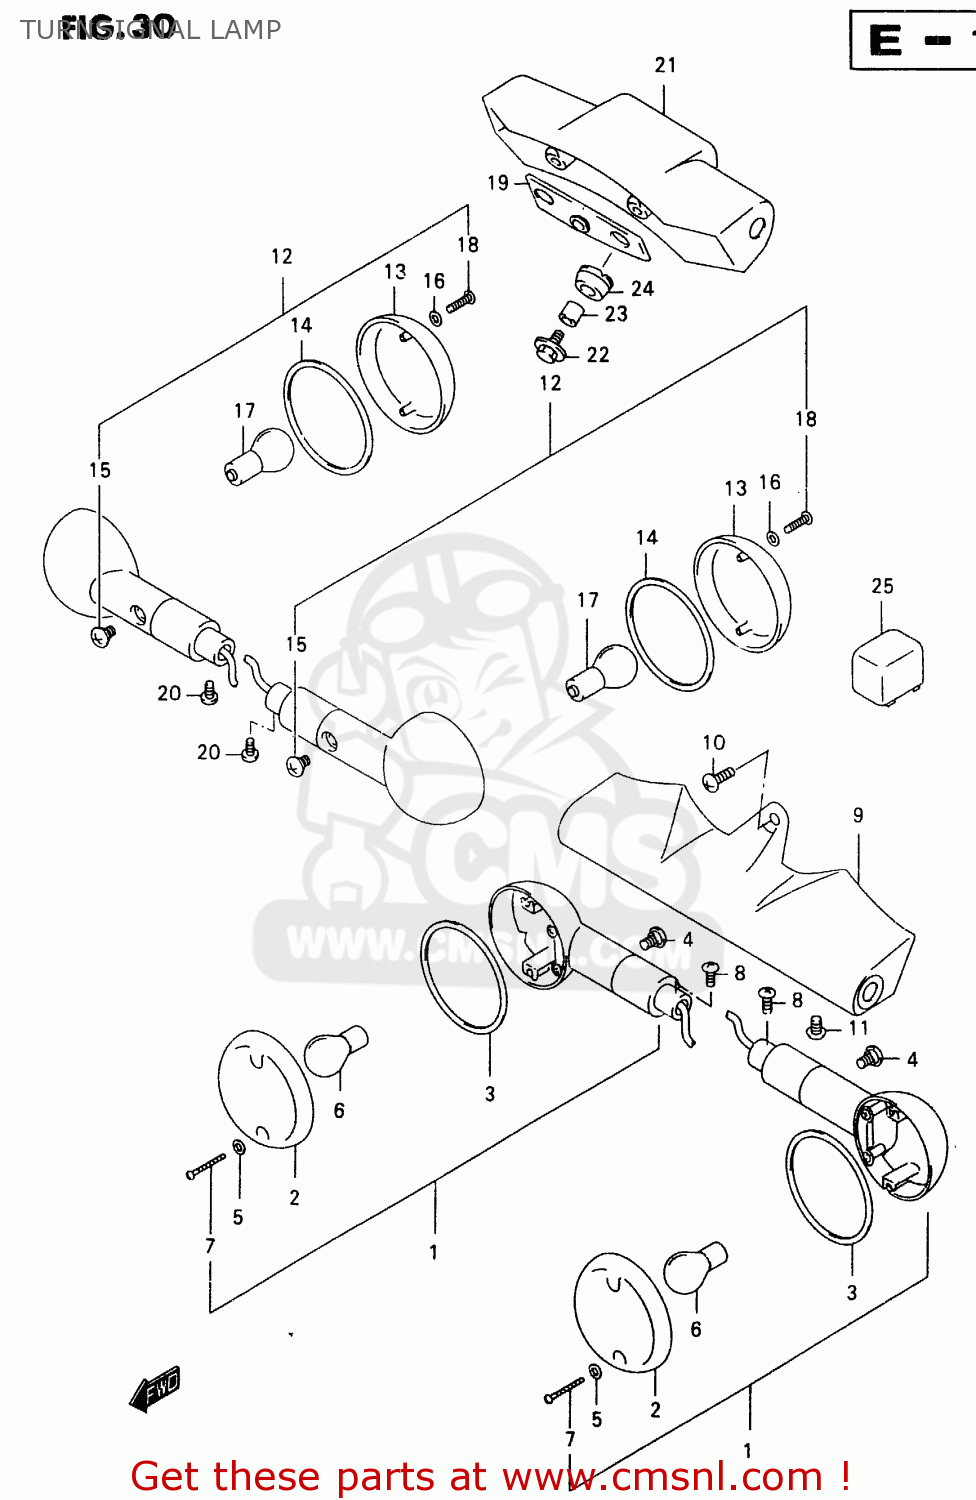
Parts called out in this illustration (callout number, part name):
1	LAMP ASSY,FR TURN SIGNAL,R
2	LENS
3	GASKET (NAS)
4	SCREW
5	GASKET (NAS)
6	BULB(12V21W)
7	SCREW
8	SCREW
9	STAY,FR TURNSIGNAL
10	SCREW(6X16)
11	SCREW(8X16)
12	LAMP ASSY,RR TURNSIGNAL,R
13	LENS
14	GASKET (NAS)
15	SCREW
16	GASKET (NAS)
17	BULB(12V21W)
18	SCREW
19	CUSHION,RR TURN STAY
20	SCREW
21	STAY,RR TURNSIGNAL
22	BOLT 6X20
23	SPACER(6.5X10X10)
24	CUSHION
25	RELAY ASSY,TURNSIGNAL LAMP
